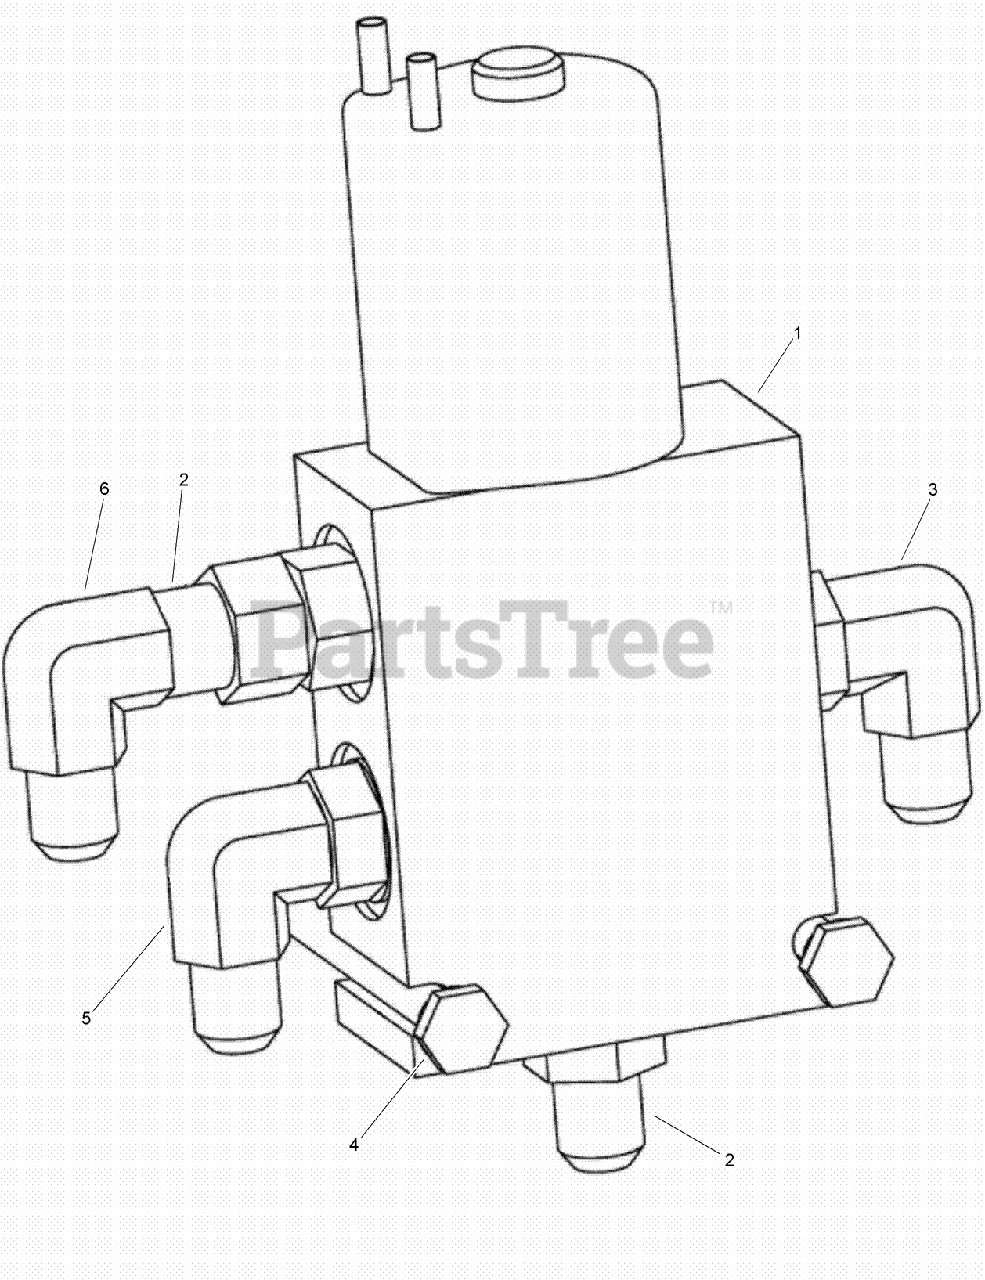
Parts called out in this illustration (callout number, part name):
1	SOLENOID VALVE ASM
2	CONNECTOR-Str Thd 3/8, 37FL-ORB 3/8
3	ELBOW-90 DEG (ADJUSTABLE 37 DEG)
4	BOLT-Hex Hd, 1/4 x 3-1/2 GR8 ZND
5	WASHER-FLAT
6	ELBOW-SWIVEL, 90 DEG
